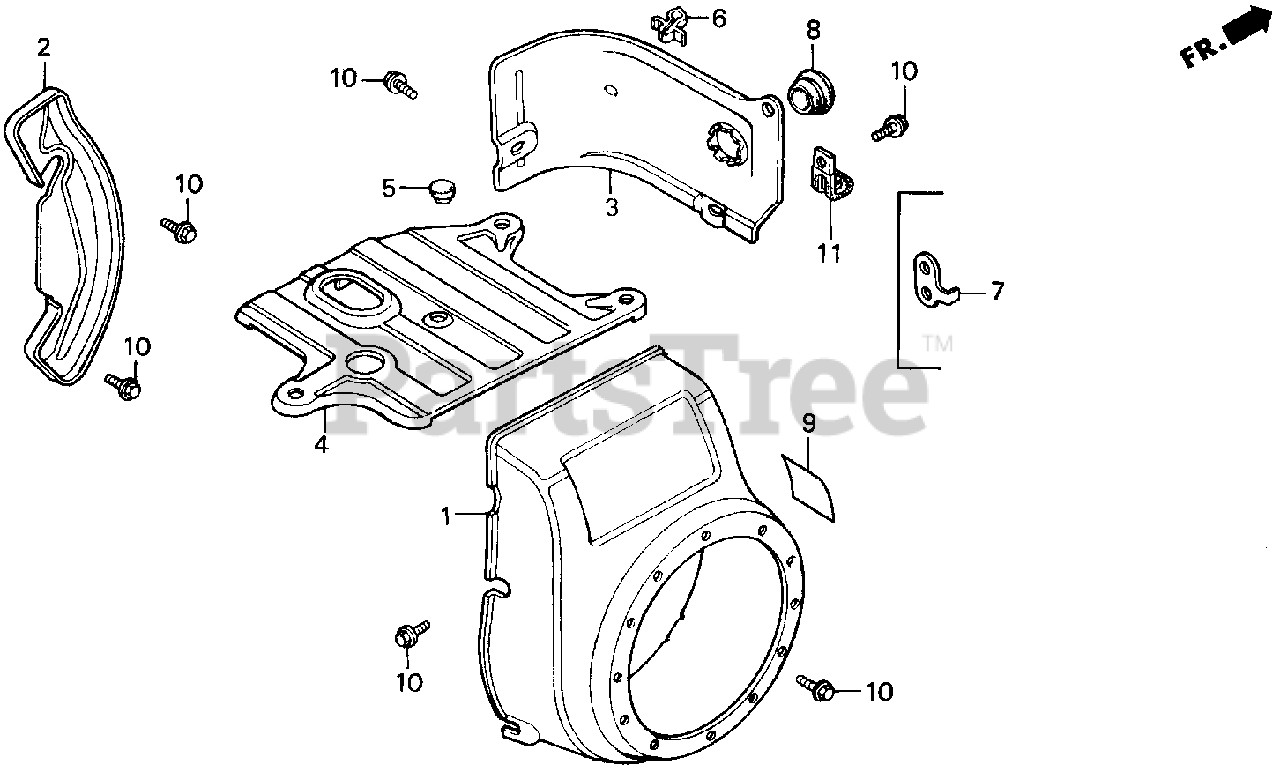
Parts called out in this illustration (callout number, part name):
1	COVER, FAN *R8* (BRIGHT RED)
2	PLATE, SIDE
4	COVER, TOP
5	GROMMET, TOP COVER
6	CLIP, IGNITION WIRE (8MM)
8	GROMMET, DRAIN HOLE
10	BOLT, FLANGE (6X12) (CT200)
11	CLIP, CABLE
